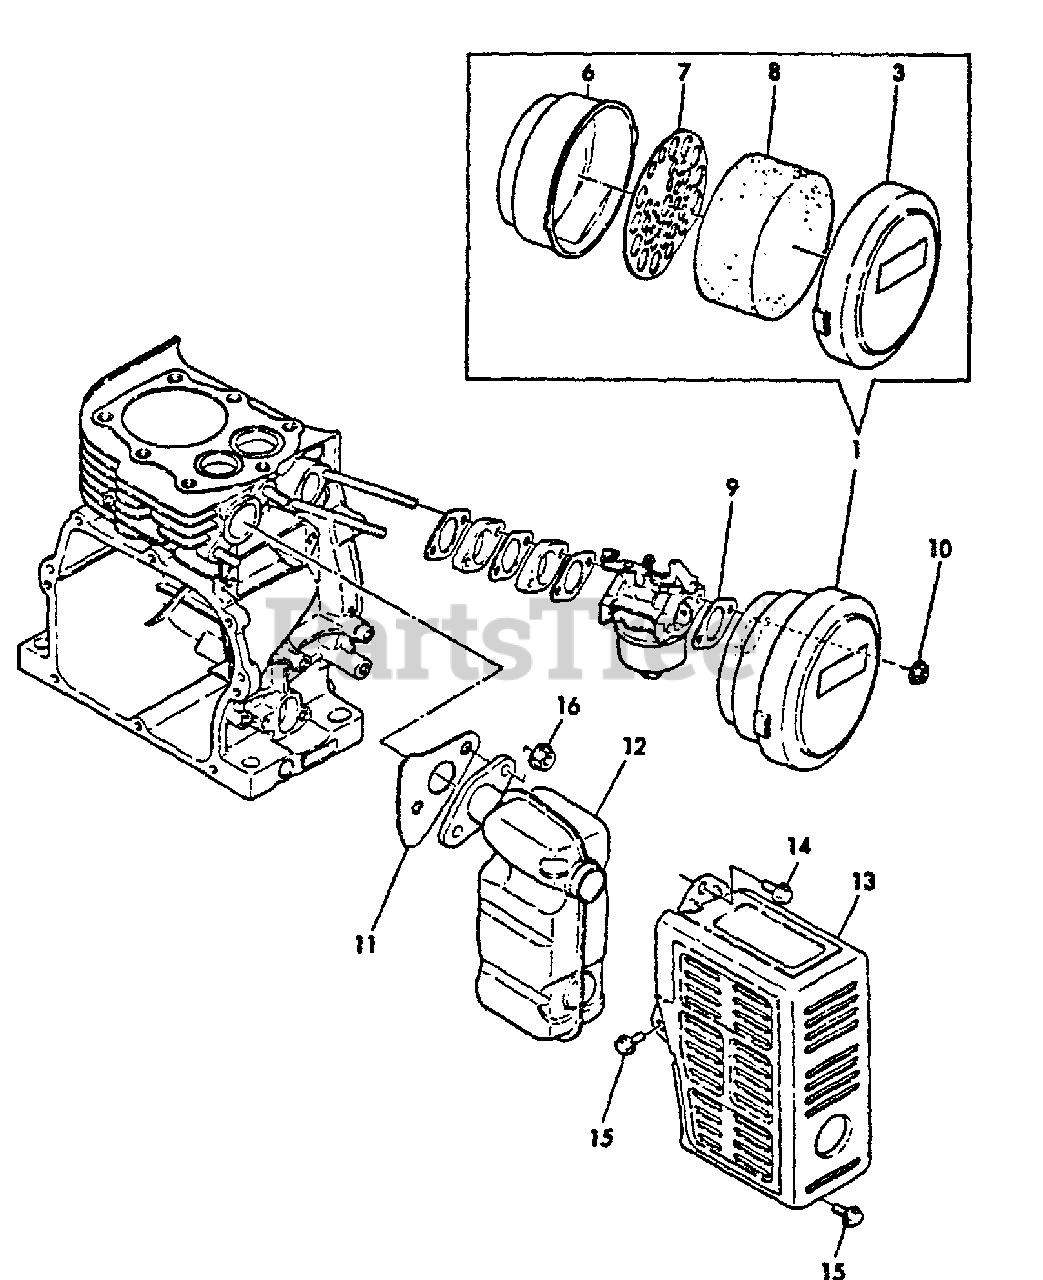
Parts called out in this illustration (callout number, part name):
1	AIR CLEANER ASSY
3	CLEANER CAP ASSY
6	CASE, AIR FILTER
7	PLATE, ELEMENT
8	FILTER, AIR
9	GASKET, INTAKE
10	NUT - 6 -- FLANGE
11	GASKET, EXHAUST
13	COVER, MUFFLER
14	BOLT - 6X12 -- PLATED
15	BOLT - 6X8 -- PLATED
16	NUT - 8
